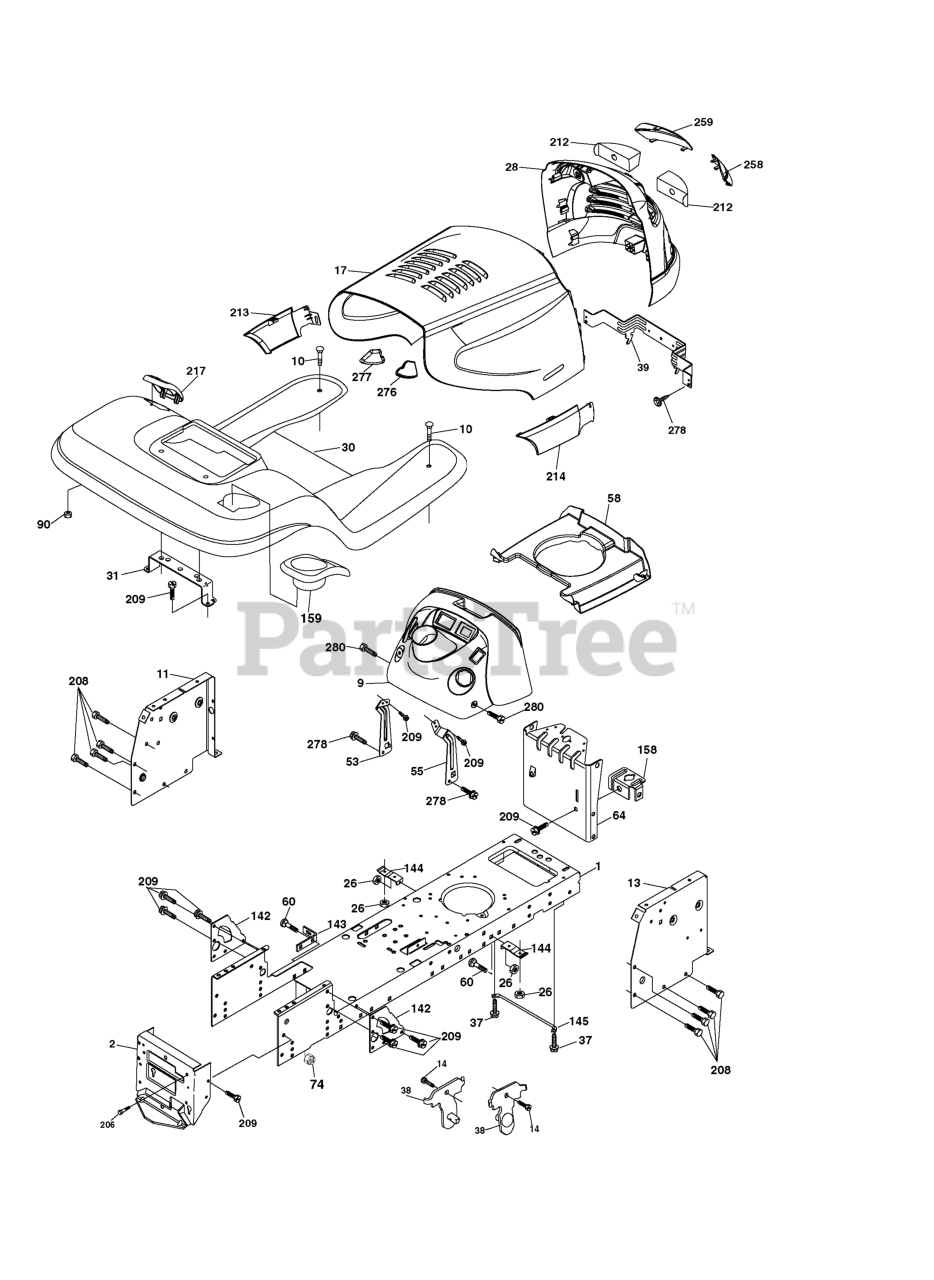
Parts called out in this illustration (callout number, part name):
1	CHASSIS STAMPING
2	DRAWBAR, 12GA
9	DASH.PANEL.GREY
10	BOLT D
11	PANEL.DASH.LH.LTX
13	PANEL DASH RH
14	SCREW LT
17	HOOD
26	NUT
28	GRILL/LENS ASSY ( YT MODEL)
30	FENDER
31	BRACKET.SUPPORT.FENDER
37	Screw Thdrol 6/16-18 x 1/2 TYT
38	BRACKET.ASM.PIVOT.MOWER.REAR
39	BRACKET PIVOT LASER
53	BRACKET DASH LH
55	BRACKET DASH RH
58	AIR DUCT P/L/LT
60	Bolt RDHD Sqnk 3/8-16 unc x 3/4
64	DASH LOWER
90	NUT.PUSH.3/16
142	PLATE REINFORCEMENT
143	BRACKET, SWAYBAR CHASSIS
144	BRKT, FOOT REST
145	ROD PIVOT CHASSIS/HOOD
158	BRACKET PARKING BRAKE
159	CUPHOLDER
206	SHOULDER BOLT 5/16-18TT
208	Screw Thdrl 3/8-16 x 1/2
209	SCREW, 3/8-16X3/4
212	INSERT LENS
213	SKIRT SIDE LH
214	SKIRT SIDE RH
217	CONSOLE FUEL WINDOW
258	LENS ELITE CLEAR RH
259	LENS ELITE CLEAR LH
276	BUMPER HOOD RH
277	BUMPER HOOD LH
278	SCREW
280	SCREW 3/8-16X1
